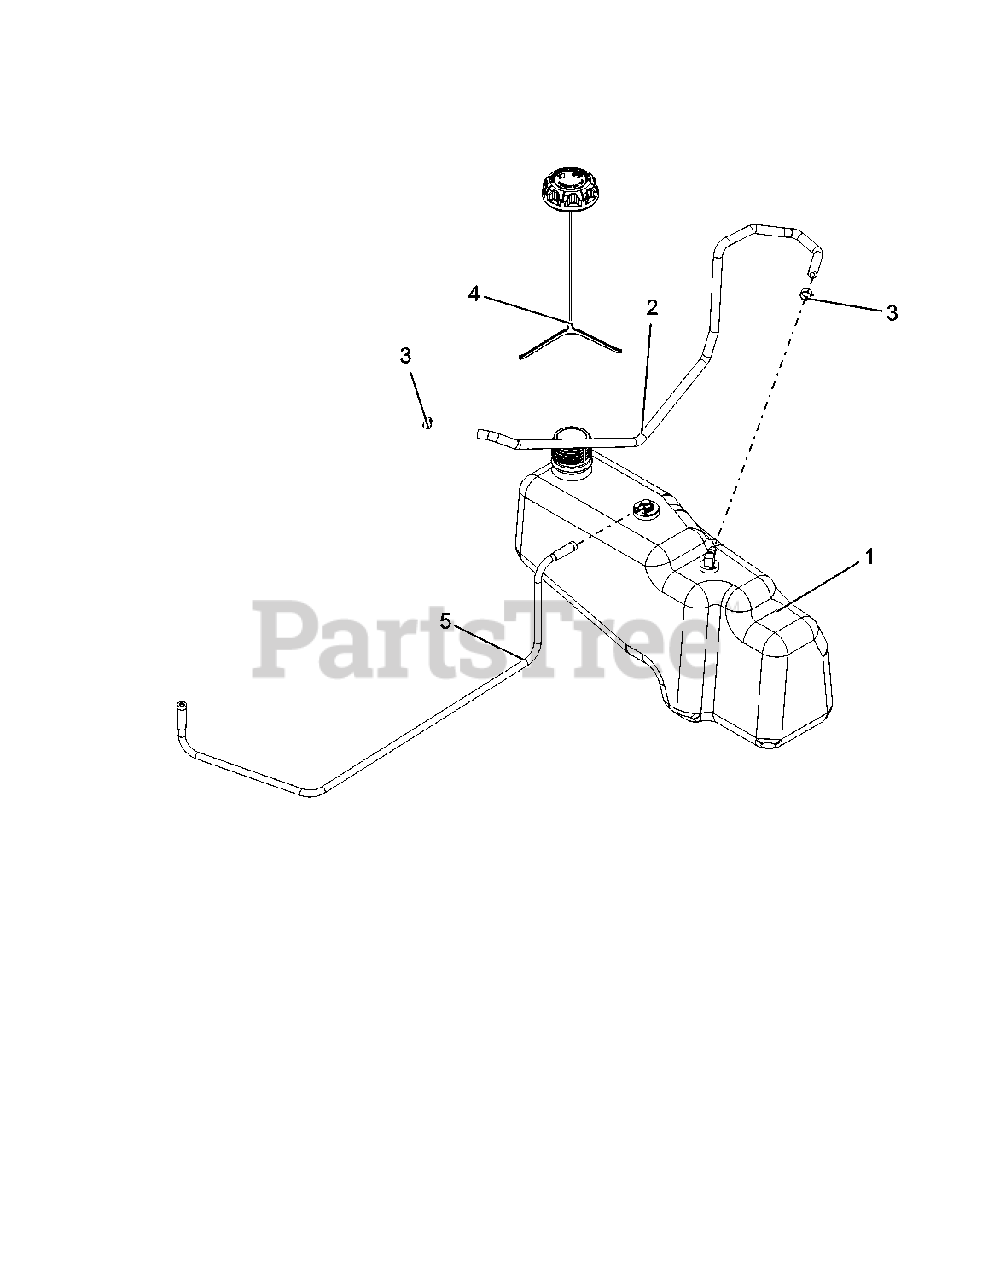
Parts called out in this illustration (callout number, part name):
1	ASM,TANK NON-PERM FUEL
2	HOSE, .25 LOW-PERM BULK GAS
3	CLAMP, FUEL LINE
4	CAP, FUEL VENT-IN 2.25" RATCH.
5	VENT LINE, B&S
